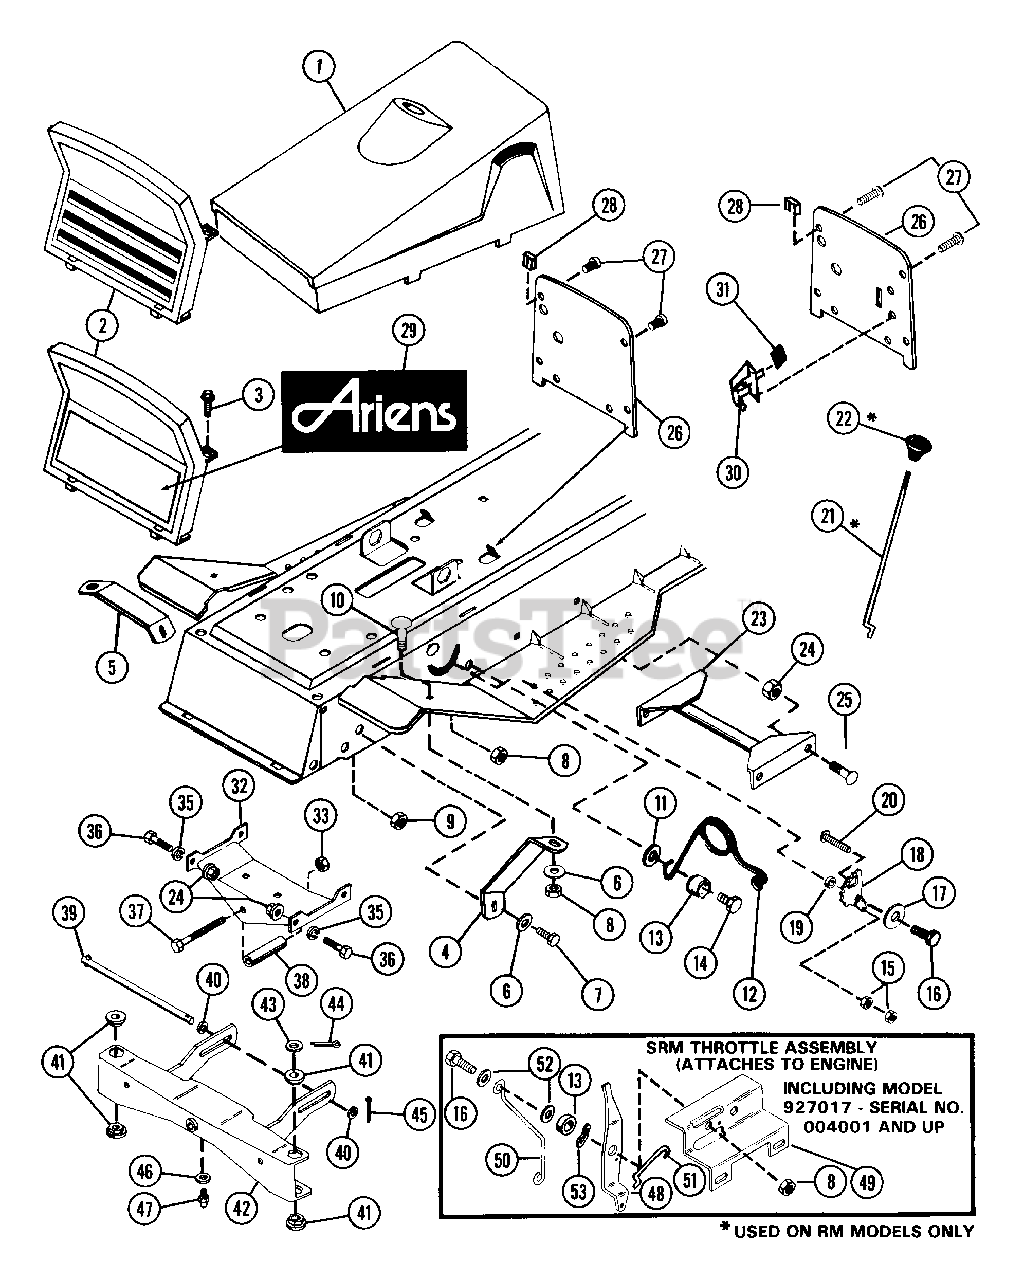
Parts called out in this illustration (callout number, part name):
2	GRILLE
2	GRILLE INSERT & SHELL ASSEMBLY
3	BLT-SERHFWH .25-20X.50 PL
4	FENDER BRACE
4	L H FENDER BRACE
5	RH FENDER BRACE
6	WSHR-FL-STL .323X.625X.062 PL
7	BLT-HEX .31-18X.63 PL GR 2
8	NUT-LK .312-18 GR A PL
9	NUT-LK-TWIN .312-18 PL
10	BLT-RDHDSQNK .31-18X.75 GR5 PL
11	WSHR-FL-STL .344X1.125X.063PL
12	SG-TORS .125X1.0X1.75
13	SPACER BUSHING .5 X .32 X .163
14	BLT-HEX .31-18X.63 PL GR 2
15	NUT 8-32 PL
16	BLT-HEX .31-18X1.00 PL GR 2
17	WSHR-FL-STL .38X.875X.083 PL
18	BRAKE LATCH
19	SPACER -SHLD .344X.500X.469
20	SCR-MCH 8-32X1.00 SLTR PL
21	PARKING BRAKE ROD
22	KNOB
23	FRAME BRACE
24	NUT-FLG. .312-18 PL
25	BLT-RDHDSQNK .312-18X.62SHTPL
26	DASH PANEL W/SILK SCREEN
26	DASH PANEL W/SILK SCREE
27	SCR-MCH 10-32X.50 CRFLSTRSEMS
28	PLASTIC GROMMET
29	DECAL - GRILLE
30	THROTTLE CONTROL
31	KNOB
32	AXLE BRACKET
33	NUT-LK-CTR .50-13
35	WSHR-LK .375X.094 MED PL
36	BLT-SERRDHD SL .31-18X.75 YZ
37	BLT-HEX .50-13X4.00 PL GR2
38	TUBE AXLE PIVOT
39	HANGER PIN
40	WSHR-FL-STL .505X.880X.072 PL
41	FLANGE BUSHING
42	AXLE
43	WSHR-FL-STL .755X1.375X.062 PL
44	PIN-COTR .12 X 1.25 PL
45	PIN-COTR .09X.75 PL
46	WSHR-FL-STL .265X.500X.087 PL
47	SPIN DRIVE ZERK FITTING
48	LEVER - THROTTLE
49	BRACKET - THROTTLE
50	THROTTLE BRACE
51	LINK
52	WSHR-FL-STL .328X.875X.062 PL
53	WAVE WASHER .531X.781X.125FH
